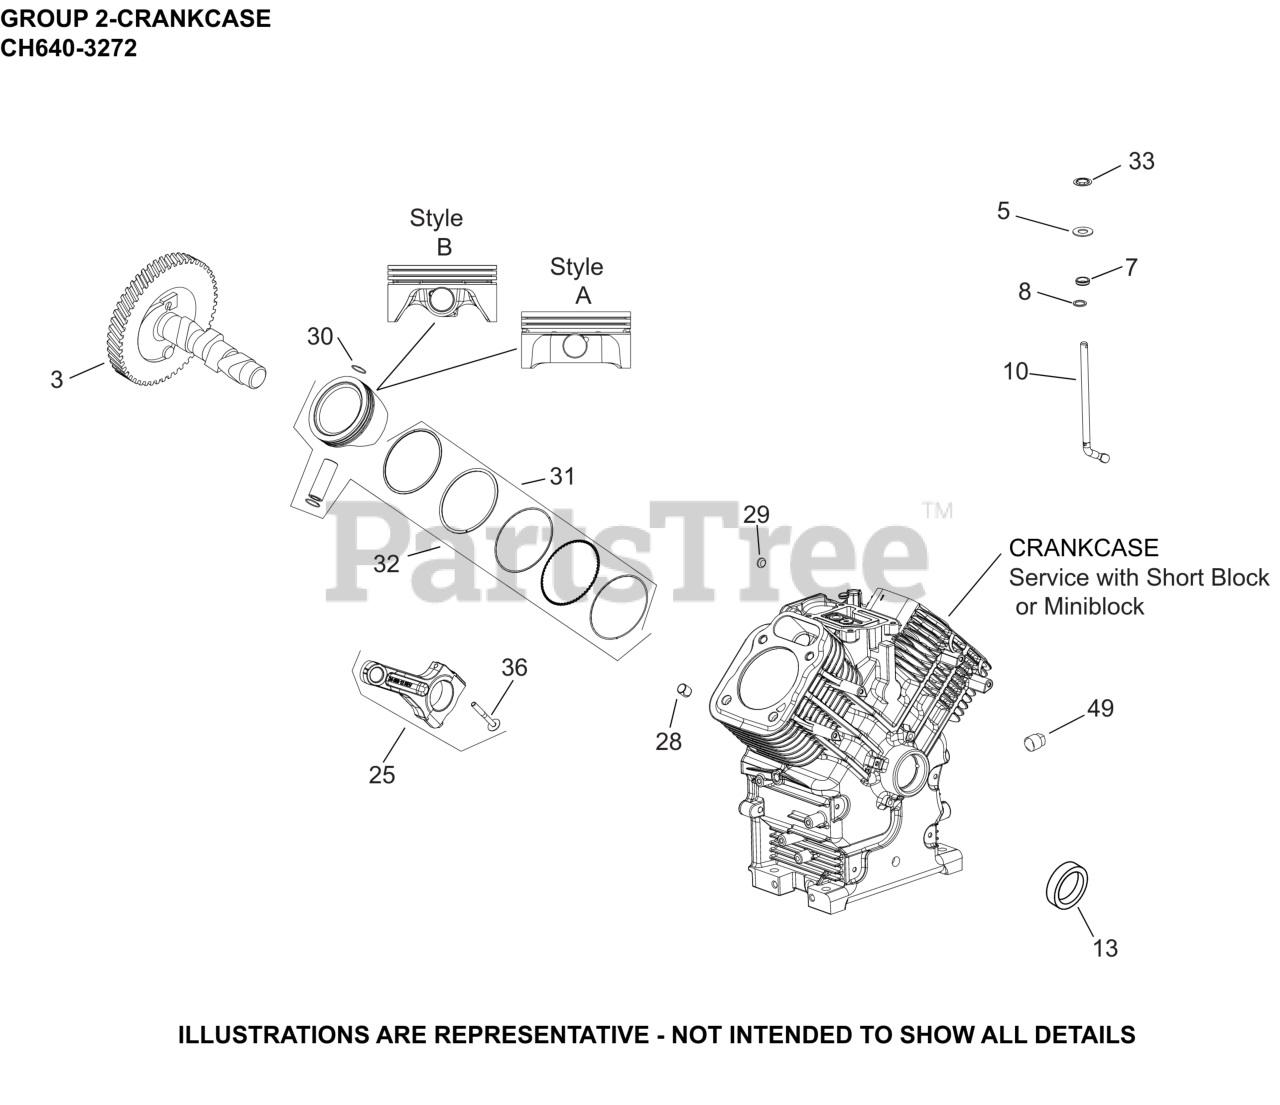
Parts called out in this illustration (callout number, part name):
3	KIT, CAMSHAFT
5	WASHER, FLAT 9 MM
7	SEAL, GOVERNOR CROSS SHAFT
8	WASHER, FLAT 11/32"
10	SHAFT, GOVERNOR CROSS
13	SEAL, OIL (HELIX LIP)
25	ROD, ASSEMBLY CONNECTING
28	PIN, LOCATING
29	PLUG, CUP
30	RETAINER, PISTON PIN
31	RING SET (STD) STYLE B
31	RING SET (.08) STYLE B
31	RING SET (.25) STYLE B
31	RING SET (.50) STYLE B
32	KIT, PISTON (STD) STYLE B
32	KIT, PISTON (.08) STYLE B-(#DSC)
32	KIT, PISTON (.25) STYLE B
32	KIT, PISTON (.50) STYLE B
33	RETAINER, RING
36	KIT, ROD BOLTS-(#25086677S)
49	PLUG, SQ HD PIPE 3/8"
